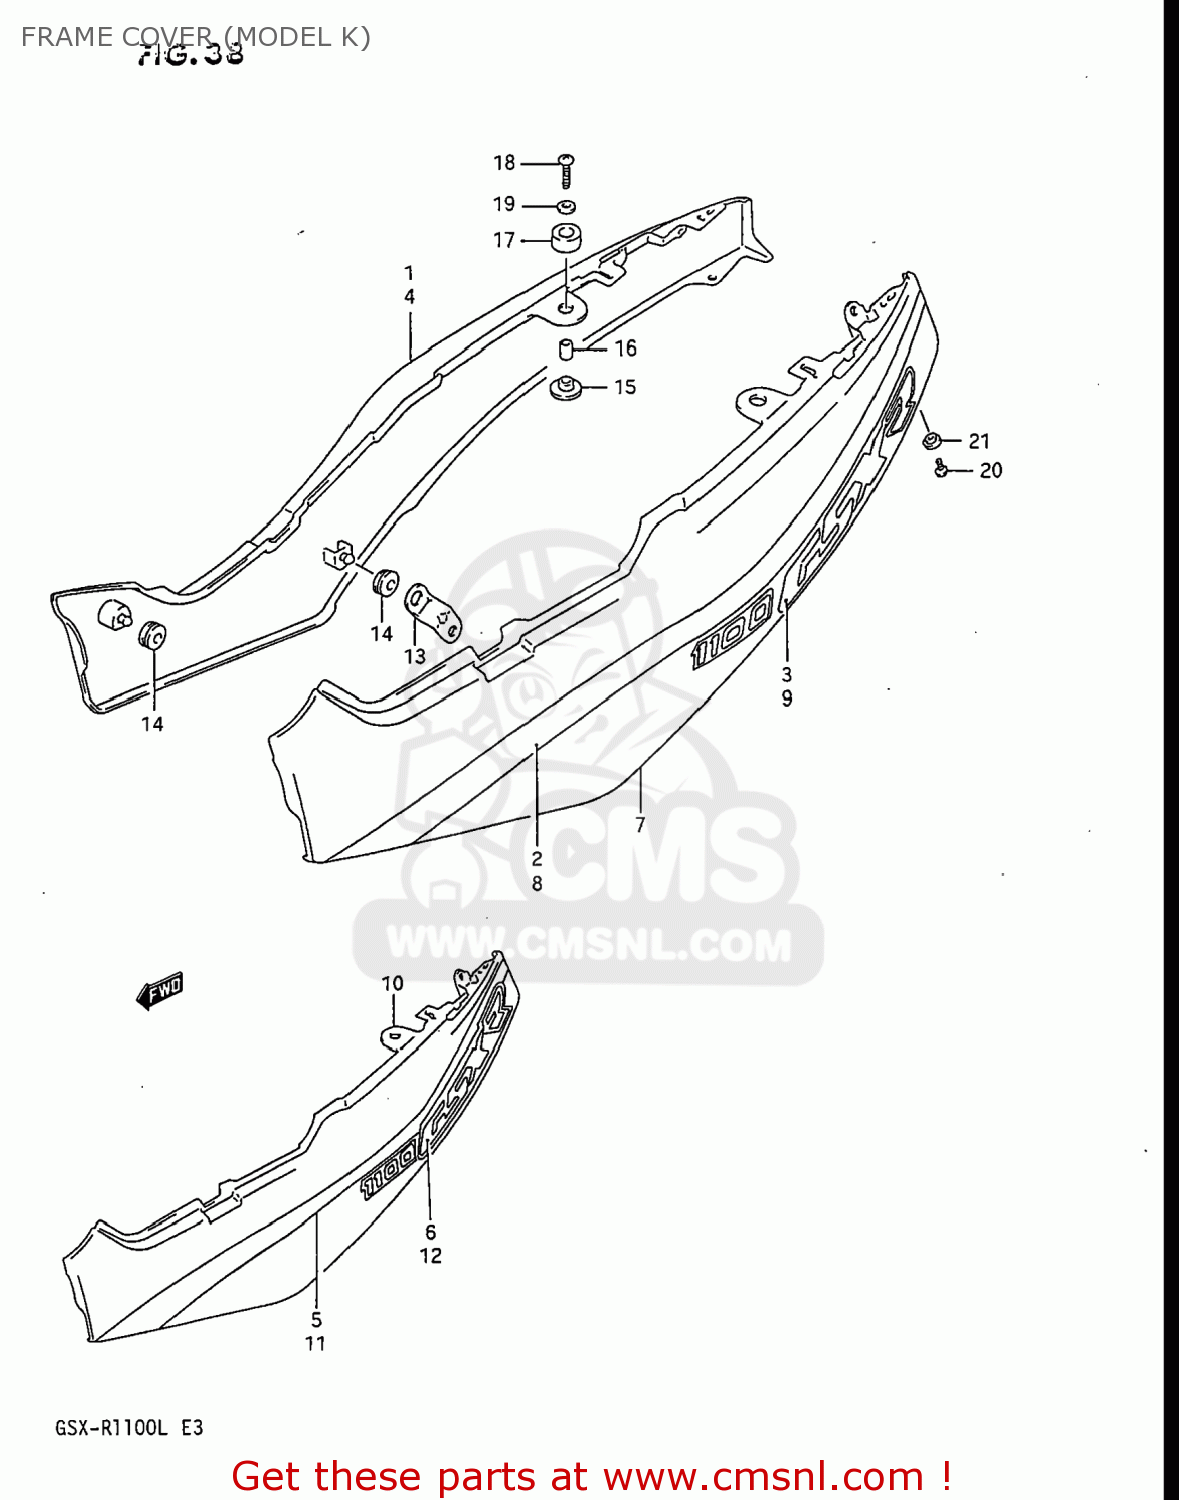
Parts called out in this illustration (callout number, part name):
1	COVER,FRAME,RIGHT
2	TAPE,FRAME COVER,RIGHT (WHITE)
3	EMBLEM,FRAME COVER,RIGHT
4	COVER,FRAME,RIGHT
5	TAPE,FRAME COVER STRIPE
6	EMBLEM,FRAME COVER,RIGHT
7	COVER,FRAME,LEFT
8	TAPE,FRAME COVER,LEFT (WHITE)
9	EMBLEM,FRAME COVER,LEFT
10	COVER,FRAME,LEFT
11	TAPE,FRAME COVER STRIPE
12	EMBLEM,FRAME COVER,LEFT
13	BRACKET,FRAME COVER
14	CUSHION
15	CUSHION,FRAME COVER LWR
16	SPACER
17	CUSHION,TAIL COVER UPR
18	SCREW
19	WASHER
20	SCREW, FRONT & REAR
21	WASHER(5.2X14X1.5)
